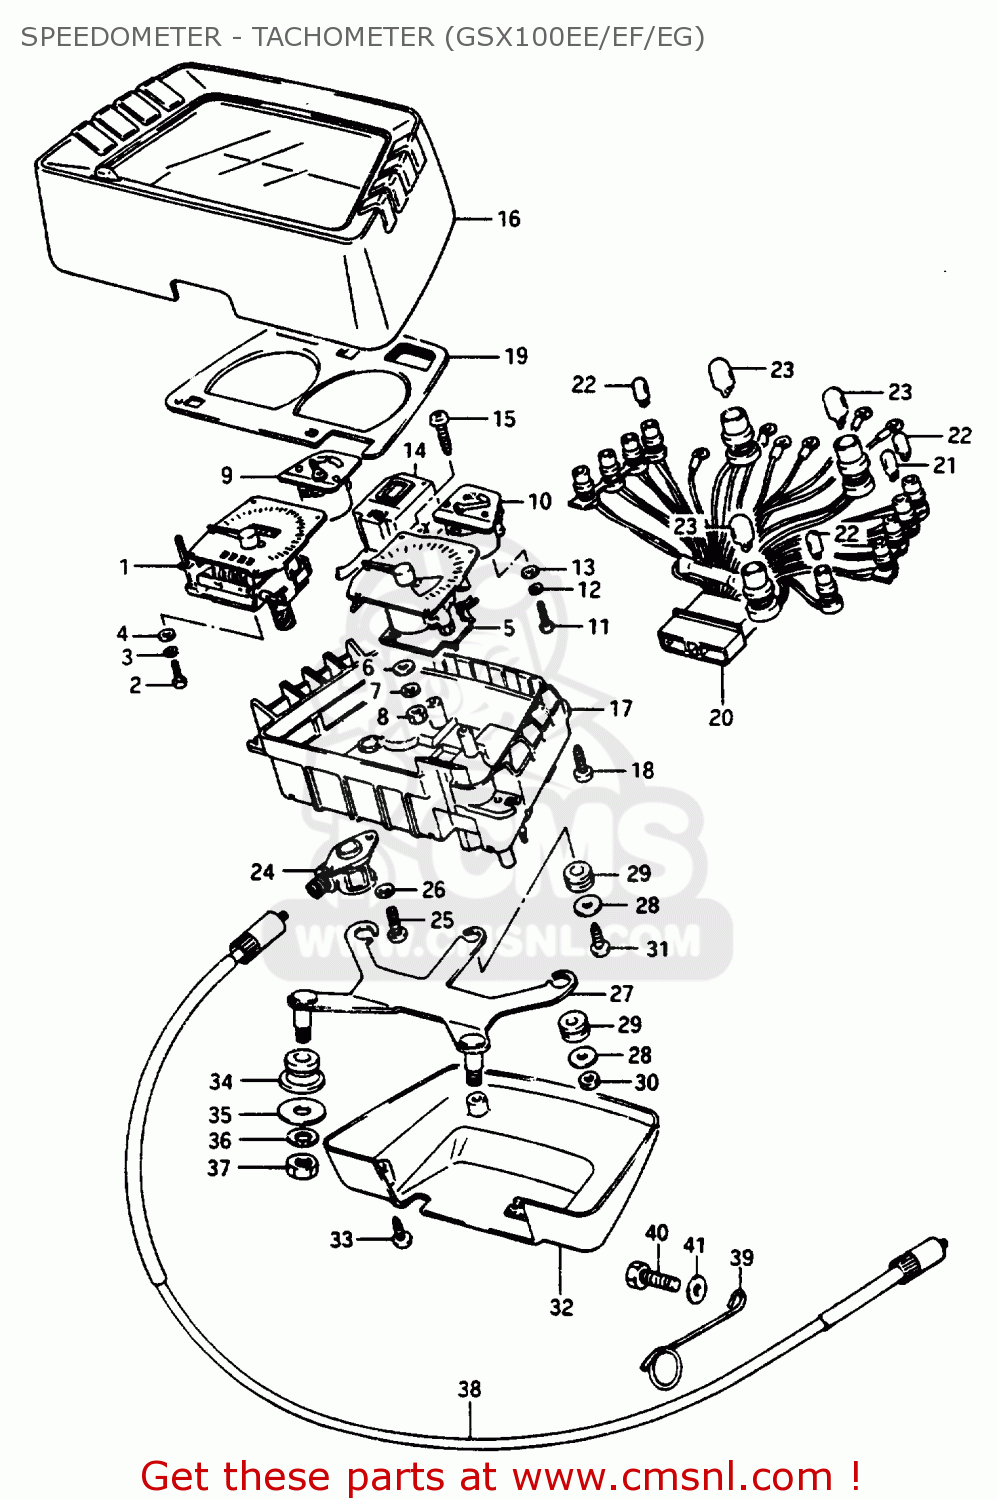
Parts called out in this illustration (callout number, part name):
1	SPEEDOMETER (KILO)
2	SCREW
3	LOCK WASHER
4	WASHER 3.3X8X0
5	TACHOMETER
6	WASHER
7	LOCK WASHER
8	NUT 4MM
9	METER,FUEL
10	METER,OIL TEMPERATURE
11	SCREW
12	LOCK WASHER
13	WASHER 3.3X8X0
14	INDICATOR ASSEMBLY,GEAR POSITION
15	SCREW
16	HOOD,METER
17	CASE,METER
18	SCREW
19	PLATE,METER WINDOW
20	SOCKET, METER
21	BULB(12V1.7W,WB372,T7)
22	BULB(12V3W,WB371,T7)
23	BULB(12V3.4W,T10,BF175-01450A)
24	GEAR BOX,SPEEDOMETER
25	SCREWM4X0.7X10
26	LOCK WASHER
27	BRACKET,METER
28	WASHER,COMBINATION METER
29	CUSHION
30	NUT 4MM
31	SCREW
32	COVER,METER,UNDER
33	SCREW
34	CUSHION,METER BRACKET
35	WASHER (8.5X20X1.6)
36	WASHER,LOCK,8.
37	NUT
38	CABLE ASSY,SPEEDOMETER
39	CLAMP,SPEEDOMETER CABLE
40	BOLT, UPPER
41	WASHER
